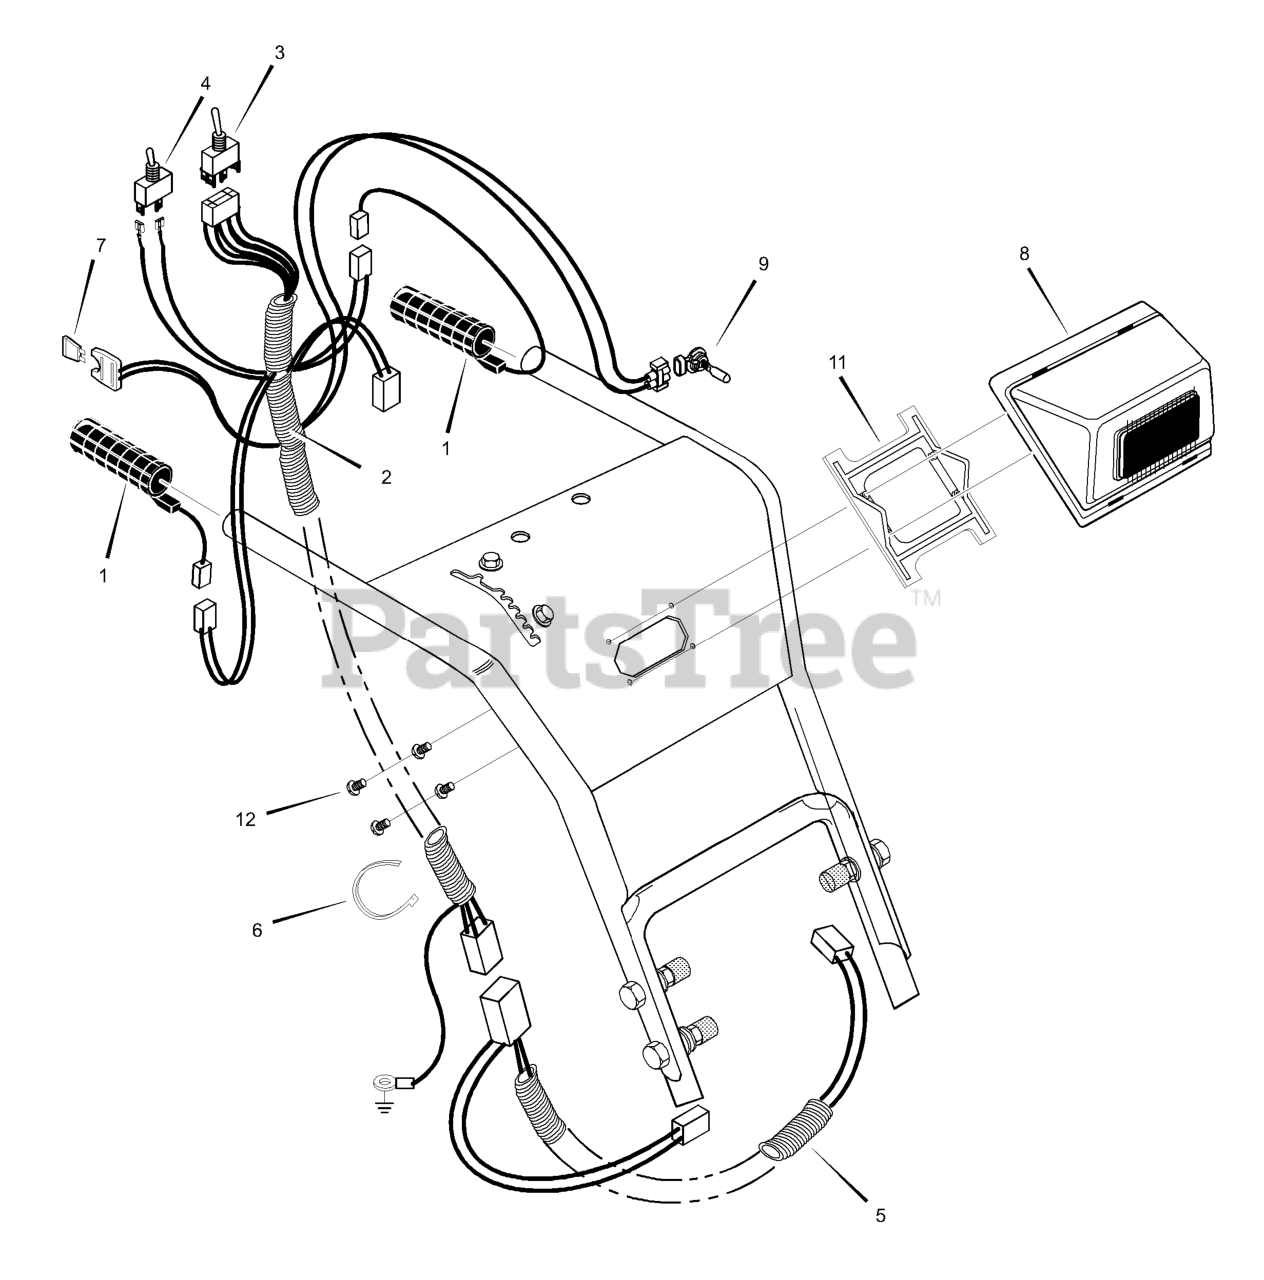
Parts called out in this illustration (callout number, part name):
1	GRIP, HEATED
2	WIRE HARNESS, UPPER
3	SWITCH, CHUTE ROTATION
4	SWITCH, HEATED GRIP
5	WIRE HARNESS, LOWER
6	TIE, CABLE
7	FUSE, 7.5 AMP AUTOMOTIVE
8	HEADLAMP HOUSING
9	HEADLIGHT ASSY
11	BRACKET, HEADLAMP
